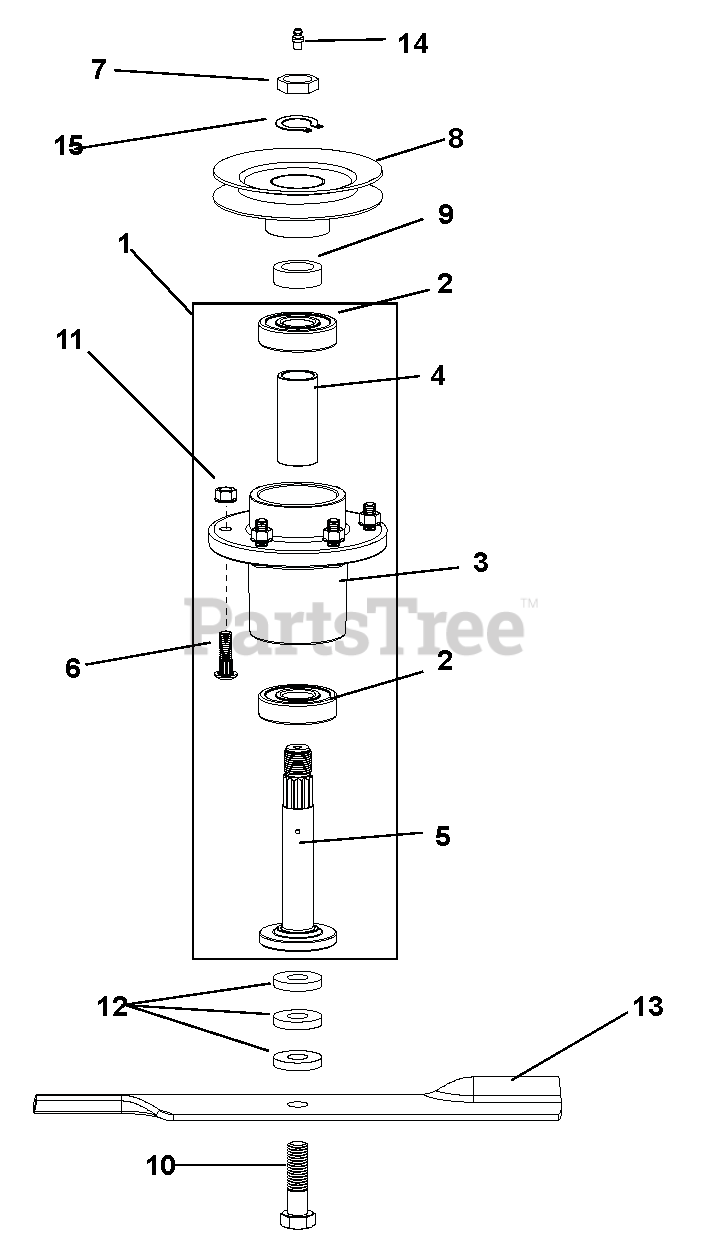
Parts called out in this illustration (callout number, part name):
1	ASSY, SPINDLE S/O
2	BEARING, 6305LLC
3	HOUSING, SPINDLE W/STUDS
4	SPACER, 1.250X1.000X2.780
5	SHAFT, SPINDLE 3/4-16
6	BOLT, 3/8-16X1.25RDHD RIBNKS/O
7	NUT, 3/4-16 FLANGE GR8 Y
8	PULLEY, SMALL W/TALL HUB
8	SPLINE, SPINDLE PULLEY OFFSET
8	HUB, LARGE PULLEY/ TALL
9	SPACER, SPINDLE TOP-PULLEY
10	BOLT, 5/8-11 X 2.00 HEX 8 Y
11	NUT, 3/8-16 STD HEX GR5 Y
12	SPACER, BLADE BOLT
13	16.5" BLADE, 48" DECK
13	18.0" BLADE, 52" DECK
14	FTG, 1/4-28 STRGT GREASE ZERK
15	RING RETAINER S/O
